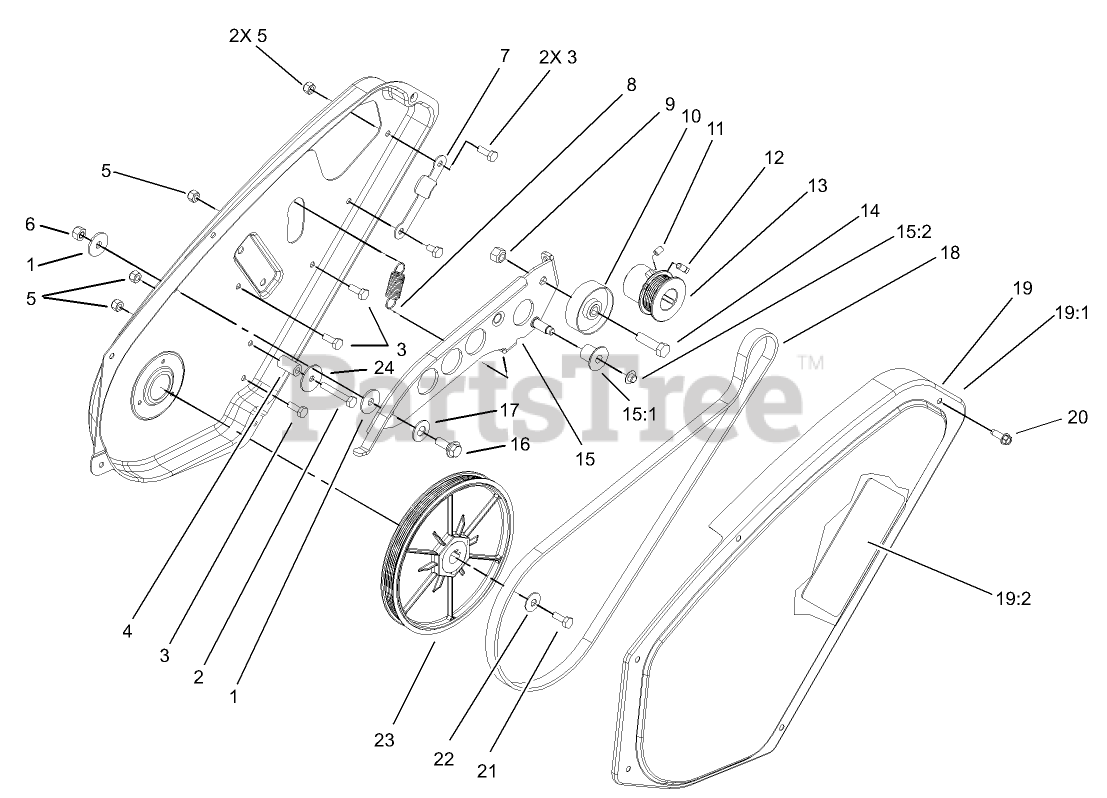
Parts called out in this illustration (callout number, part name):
1	WASHER-PIVOT
2	SCREW-HH
3	SCREW-HH
4	SLEEVE-GUIDE, BELT
5	NUT-LOCK, NI
6	NUT-LOCK, NI
7	BELT-GUIDE
8	SPRING
9	NUT-LOCK, CONE
10	PULLEY-IDLER
11	SCREW-HSH
12	SCREW-SQH
13	PULLEY
14	SCREW-HH
15	BRAKE-ARM
15:1	ROLLER-BRAKE
15:2	NUT-PUSH
16	SCREW-SHOULDER
17	WASHER
18	BELT-DRIVE
19	DRIVE COVER ASM
19:1	DECAL-WARNING
19:2	DECAL-ROUTING, BELT
20	SCREW-HWHTF
21	SCREW-HH
22	WASHER-BELLEVILLE
24	WASHER-FLAT
